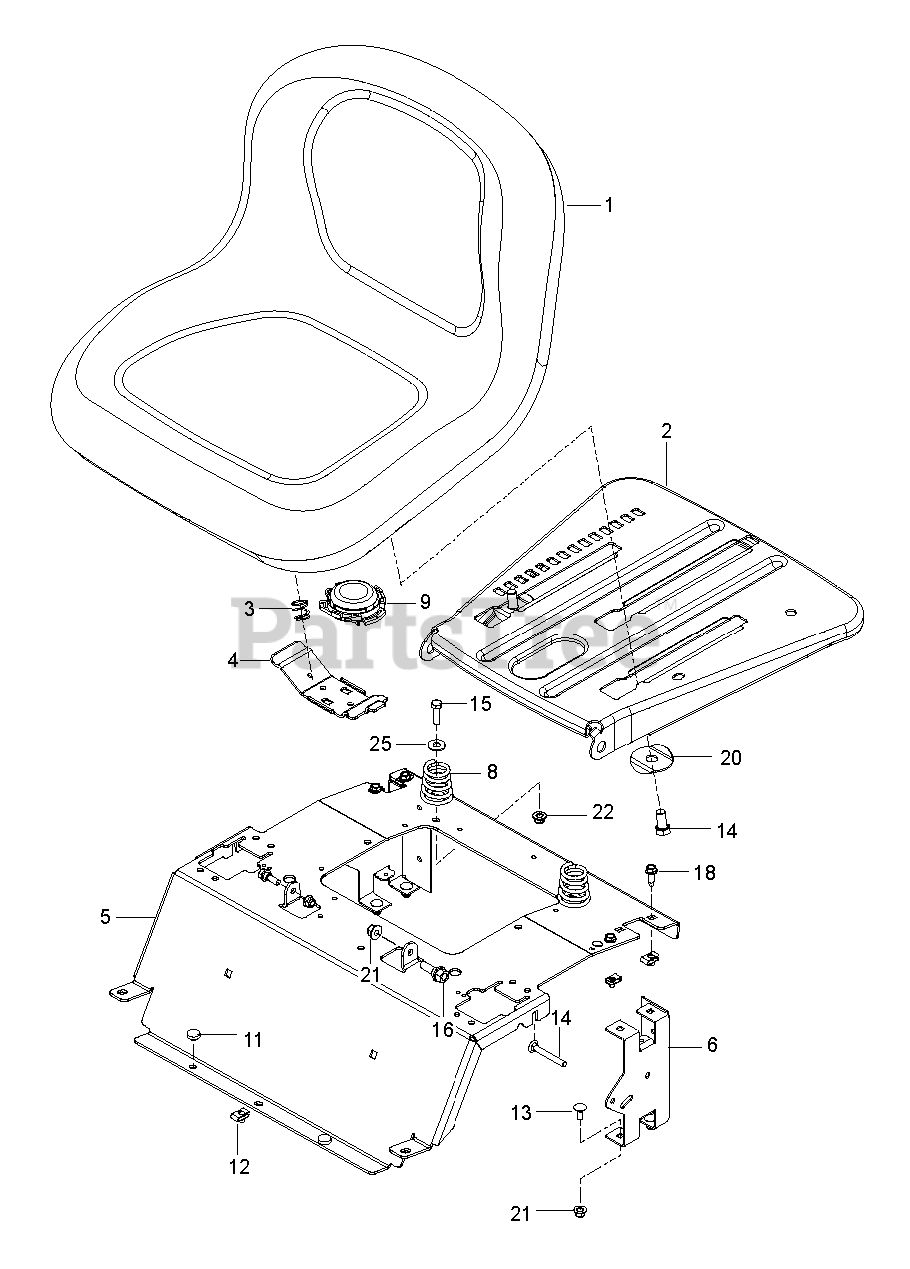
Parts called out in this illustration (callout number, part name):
1	SEAT.TH150.MS498.GRY.HUSQ.TEX
2	PLATE.PNT.SEAT.SLIDE.3PT.EDIP
3	SPRING.LATCH.SEAT.TEX
4	HANDLE.SLIDE.SEAT.TEX.BLACK
5	SUPPORT.SEAT.RZ.HUSQ.ORANGE
6	SUPPORT REAR SEAT BLACK
8	SPRING.COMPRESS.SEAT.TAPERED
9	SWITCH.SEAT.DELTA.OPC.
11	GROMMET.BUMPER
12	U-CLIP 5/16-18 NUT RETAINER
13	BOLT 5/16C X 3/4" CARRIAGE
14	RHSNB 5/16-18 X 2-1/2 GR5 ZD
15	BOLT
16	BOLT, SHOULDER
18	SCREW.THDROL.5/16-18X3/4.TTY
20	WASHER.WINGED.3/8ID.1.5OD
21	5/16-18 NYLOC FLANGE NUT
22	NUT 3/8-16 HEX FLG NYLOC ZD
25	RP WASHER 3/8 FLAT
